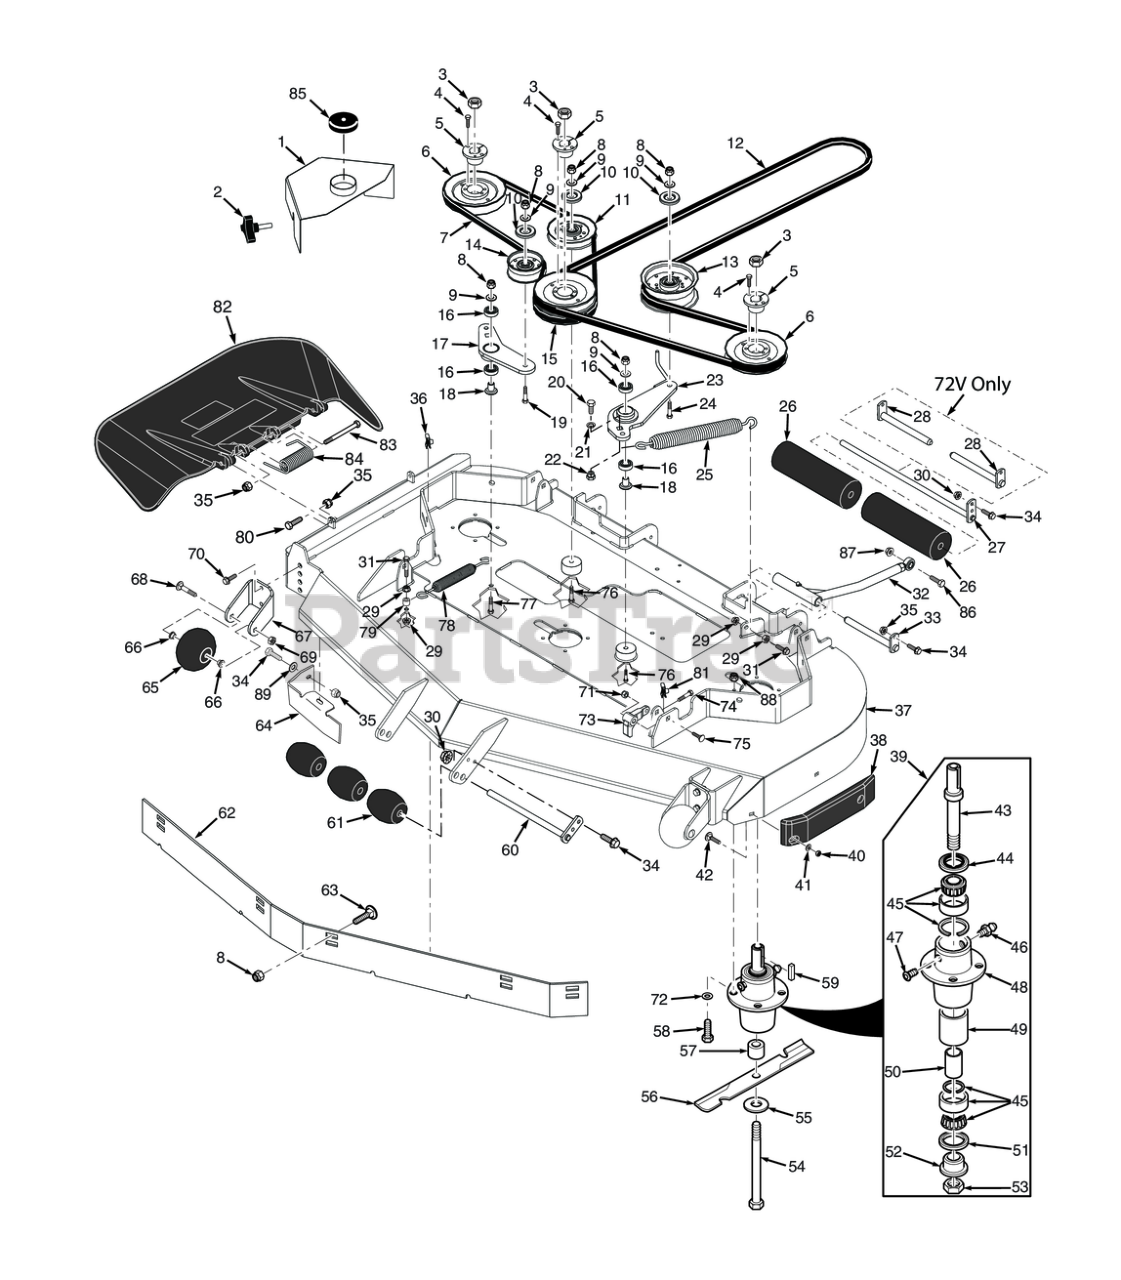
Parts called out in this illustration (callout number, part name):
1	Belt Cover, LH (INCL 85)
1	Belt Cover, RH (INCL 85)
2	Knob, w/stud 3/8-16 x 1-1/4"
3	Hex Locknut, Elastic Stop, 3/8-16
4	Bolt, Hex Head 1/4-20 x 1" Grade 8 Black
5	Hub, Tapered 1-1/8" Bore
6	Pulley, Tapered Bore 6.33" Dia.
7	Belt, Deck Drive R.H.
8	HEX NUT, ELASTIC STOP LOCK, 3/8-16
9	Flatwasher, 3/8 (.391 x .938 x .105 HD) Grade 8
10	Quick Pin, 5/16" Dia.
11	IDLER PULLEY, "V" GROOVE
12	Belt, Cutter Deck Drive - Cat
13	Pulley, Idler 5" Dia.
14	Pulley, 3-1/2" Dia.
15	Pulley, Double Groove 6.33" Dia.
16	BEARINGS, BALL, NEUTRAL RETURN
17	ldler Arm Assembly, R.H. Drive
18	Pivot, Idler Short
19	Capscrew, Hex Head 3/8-16 x 2-1/2"
20	Bolt, Hex Head 7/16-14 x 1"
21	Lockwasher, 7/16� Spring
22	Boss, Spring Anchor - LH
23	Idler Arm
24	Bolt, Hex Head 3/8-16 x 3" - 52"
25	Spring, L.H. Deck Drive
26	Wheel, Anti-ScalpRelief Fitting, Tapered Spindle
27	Roller Shaft (small frame)
29	NUT, 3/8-16 SERRATED FLANGE HEX HEAD
30	Nut, Flange Head Elastic Stop 5/16-18
31	Bolt, Hex Head 3/8-16 x 1-1/2" Grade 8 Black
32	Pusharm Assembly, LH
32	Pusharm Assembly, RH
33	Shaft Weldment, Pusharm
34	Bolt, Heax Head 5/16-18 x 1" (48V / 52V)
35	HEX NUT, ELASTIC STOP LOCK, 5/16-18
36	U-Nut, 3/8-16
37	Cutter Deck w/Decals
38	Pad, Deck Wear
39	Cutter Spindle Assembly
40	Nut, Center Lock, 5/16-18(32)
41	Flatwasher, 5/16-.344 x .688 x .065 (48V / 52V)
42	Bolt, 5/16-18 x .75 RHSN Carriage
43	Spindle Shaft, Tapered Brng
44	SEAL, 2.00 O.D. X 1.50 BORE
45	Tapered Bearing Set (Two Bearings W/Race)
46	GREASE FITTING, STR. 1/4-28 SELF TAP.
47	RELIEF FITTING, TAPERED BEARING SPINDLE
48	Housing, Spindle
49	Spacer, Outside, Cutter Spindle
50	SLEEVE, CUTTER SPINDLE
51	Seal, 2.00" O.D. x 1.625" Bore
52	SPINDLE BUSHING, BOTTOM
53	Nut , Spec ial 1 -1/ 1 6 - 1 8
54	BOLT, HEX HEAD, 5/8-11 X 9-1/2 GR.5
55	Flatwasher, 5/8-.688 x 1-3/4 x .134 HD
56	Cutter Blade, 21" (35BV & 37BV-EFI)
57	Spacer, Spindle Bottom
58	Bolt, Hex Head 5/16-18 x 1-3/4" Grade 8
59	Key, 1/4 x 1/4 x 2.0"
60	Shaft Weldment, Guide Roller
61	Wheel, Anti-Scalp
62	Baffle Custom-Cut, 61V (7-Position)
63	Carriage Bolt, 3/8-16 x 1.0"
64	Turbo Baffle, Bolt On
65	Bolt, Carriage 3/8-16 x 4"
66	Bushing, .376" I.D. Oilite
67	Bracket, Anti-Scalp Wheel
68	Bolt, Hex Head 3/8-16 x 3-1/2"
69	Bolt, Hex Head 3/8-16 x 1" Ser. Flg.
70	Capscrew, 3/8-16 x 1.0" Serrated Flange Hex Hd
71	HEX LOCKNUT, ELASTIC STOP, 7/16-14
72	Lockwasher, 5/16 (.317 x .586 x .078) Helical Spring
73	Lever, Deck Level
74	Bolt, Hex Head 3/8-16 x 2-1/2" Soecial Lock
75	Bolt, Carriage 7/16-14 x 2-1/4"
76	Bolt, Hex Head 3/8-16 x 3" - 52"
77	Bolt, Hex Head 3/8-16 x 2-1/4" - 61"
78	Spring, RH Deck Drive
79	SPACER, IDLER
80	Bolt, Hex Head 5/16-18 x 1-1/2" - Front
81	U-Nut, 3/8-16 (short)
82	Discharge Chute Advantage - Large
83	Bolt, 5/16-18 x 4-3/4" Hex Head
84	Spring, Discharge Chute
87	Nut, Center Lock 5/8-11
88	Lock Nut, 5/16-18 Elastic Stop Grade 8
89	Flatwasher, 5/16-.375 x .875 x .083 (35BV & 37BV-EFI)
